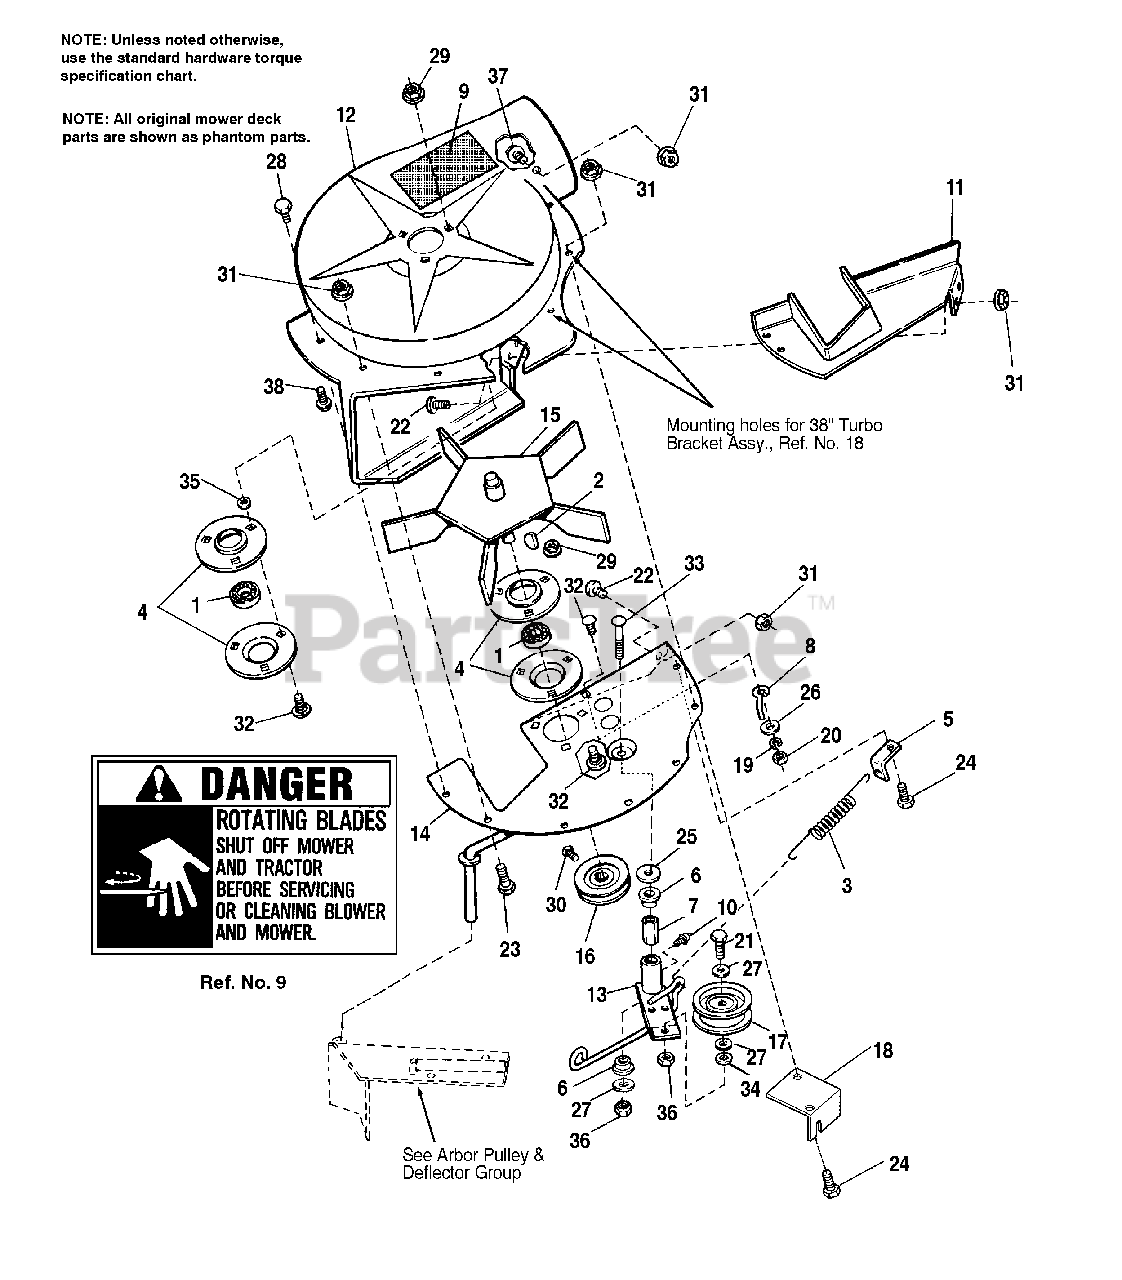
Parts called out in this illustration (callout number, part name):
2	KEY, Woodruff, Modified, .188 x .875 #61
3	SPRING, Tension
4	BEARING, Retainer
5	BRACKET, Anchor, Spring
9	DECAL, Danger, Blower
10	FITTING, Grease
11	PLATE, Cover
12	FAN HOUSING
13	LEVER ASSY, Turbo
14	PLATE ASSY.
15	FAN ASSY., 5 Blade
16	PULLEY, Driven
17	IDLER PULLEY ASSY.
18	BRACKET ASSY., Turbo
19	WASHER, Spring Lock, 5/16
20	NUT, Hex, 5/16
21	CAPSCREW, Hex Hd., 3/8-16 x 1-1/4
22	SCREW, Truss Hd., 1/4-18 x 5/8
23	CAPSCREW, Hex, 1/4-20 x 5/8
24	CAPSCREW, Hex Hd., 1/4-20 x 3/4
25	WASHER, Flat
26	WASHER, Flat, 5/16
27	WASHER, Plain, 3/8
28	CAPSCREW, Hex, Taptite, 1/4-20 x 1/2
29	NUT, Flange, Whizlock, 5/16-18
30	SETSCREW, Hex, Socket Hd., 5/16-18 x 5/16
31	NUT, Hex, Flange Lock, 1/4-20
32	CARRIAGE BOLT, 5/16-18 x 3/4
33	CARRIAGE BOLT, 3/8-16 x 2-1/4
34	WASHER, Flat, 7/16
35	PUSH NUT, 3/8
36	NUT, Hex, Jam, Center Lock, 3/8-16
37	CARRIAGE BOLT, 1/4-20 x 5/8
38	SCREW, Washer Hd., 1/4-18 x 5/8
